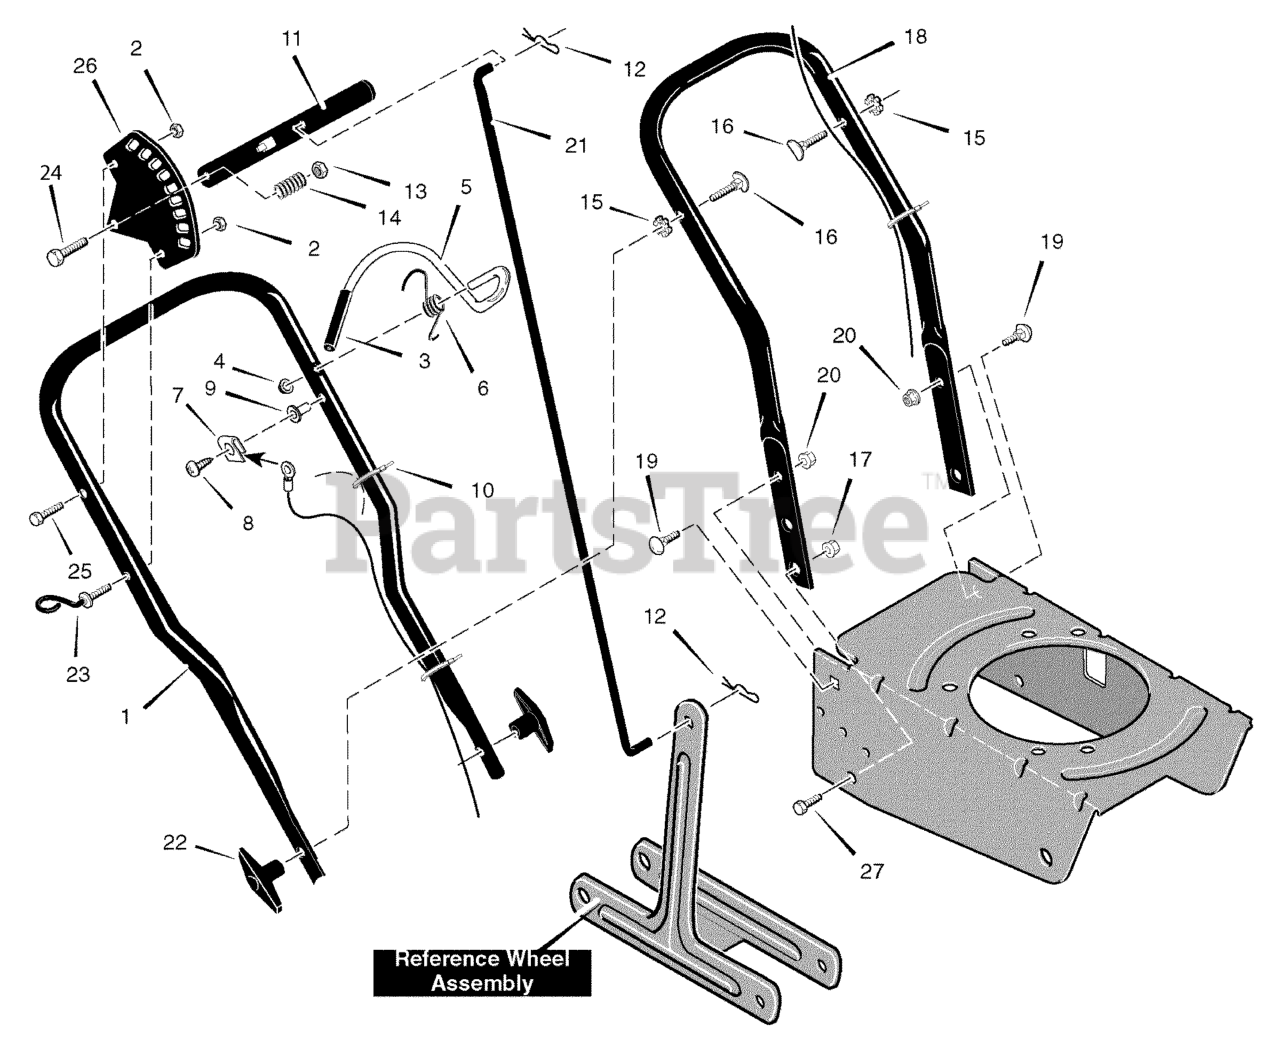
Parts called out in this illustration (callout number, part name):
1	Upper Handle
2	NUT, 1/4-20
3	Cap, Operator Control
4	Nut, Push On
5	Bail, Operator Control
6	Torsion Spring
7	Clip, Grounding
8	Screw, #6x.50
9	Insulator, Oper Control
10	Cable Tie
11	Handle, Depth
12	Hair Pin
13	NUT, 5/16-18
14	Spring, Compression
15	Washer
16	BOLT, 5/16-18X.75
17	NUT, 5/16-18
18	Lower Handle
19	BOLT, 5/16-18X.75
20	NUT, 5/16-18
21	Rod, Control
22	Wing Knob 5/16-18
23	Rope Guide
25	Screw, 1/4-20x1.25
26	Bracket, Adj. Quadrant
27	Bolt, 5/16-18x2.00
